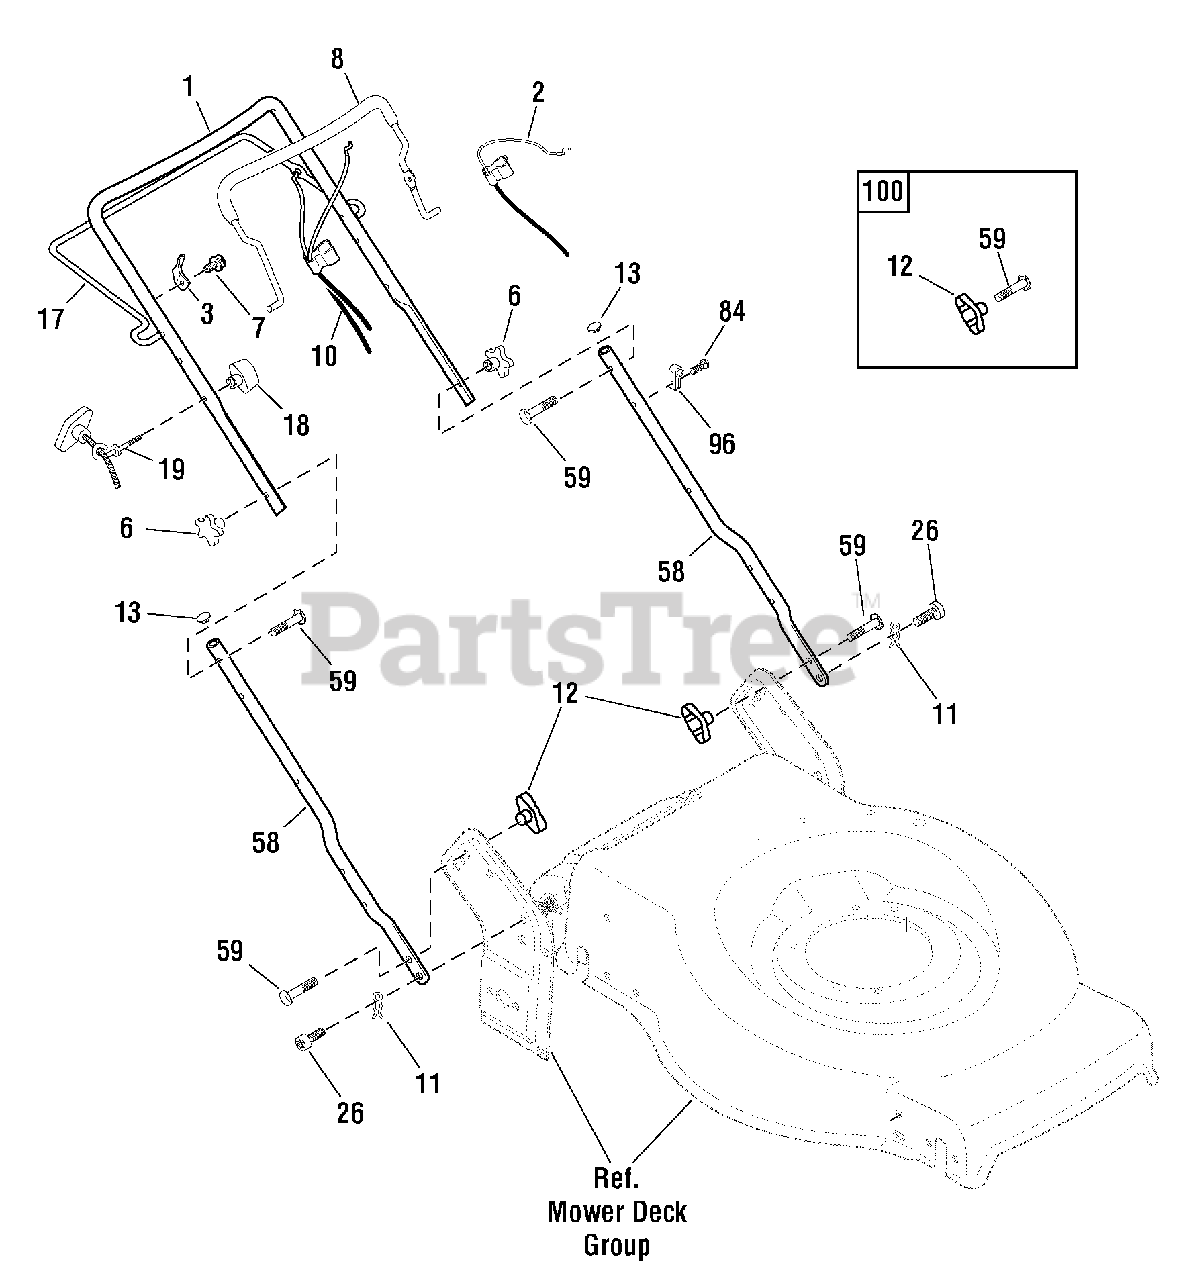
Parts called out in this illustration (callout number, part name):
1	HANDLE, Upper
3	BRACKET, Upstop
6	KNOB, Handle
7	SCREW, #10-16 x 5/8
8	CONTROL BAR
10	CABLE, Drive Control
11	HAIRPIN
12	KNOB, Handle
13	PLUG, Handle
17	BAIL, Drive Control
19	GUIDE, Rope
58	HANDLE, Lower
59	BOLT
84	FASTENER, Push
96	CLIP, Cable
100	KIT, Hardware, Handle
